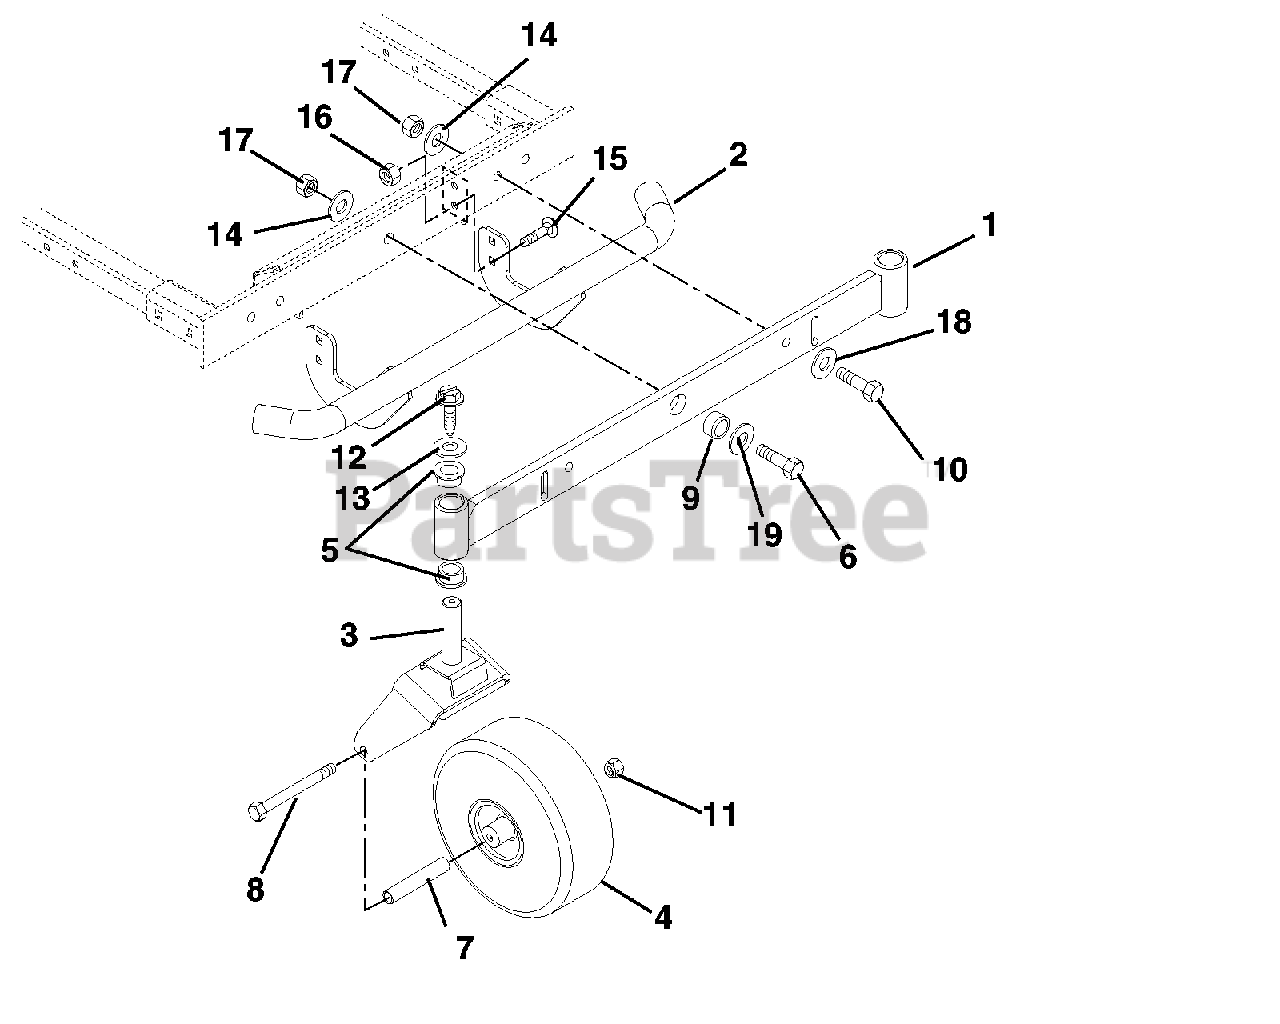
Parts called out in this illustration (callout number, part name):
1	WMT, FRONT AXLE
2	BUMPER-ZOOM
3	FORK - CASTER
4	ASSY-TIRE 4 X 11 - 4 PLY
5	BSHG-FLG 1.00X1.25X1.50X1.50EP
6	@BLT-HEX .62-11X2.50 GR5 YWZC
7	BUSH.,CASTER FORK
8	@BLT-HEX .50-13X6.50 GR5 YWZC
9	BUSHING, AXLE PIVOT
10	BLT-SHLDR .75 .625-11X2.12SHCS
11	@NUT-LK-TOP-FLG .50-13 YWZC
12	SCR-TAP .38-16X1.25 HWH TR BZC
13	WSHR-FL-STL .380X1.50X.125YWZC
14	WSHR-FLT .640X1.75X.250 YWZC
15	@BLT-RDHDSQNK .38-16X1.00 G5YZ
16	@NUT-LK-NYL-FLG .38-16 YWZC
17	@NUT-LK-NYL .625-11 YWZC
18	@WSHR-FL-STL.812X1.50X.135YWZC
19	@WSHR-FL-STL.688X1.75X.134 YWZ
